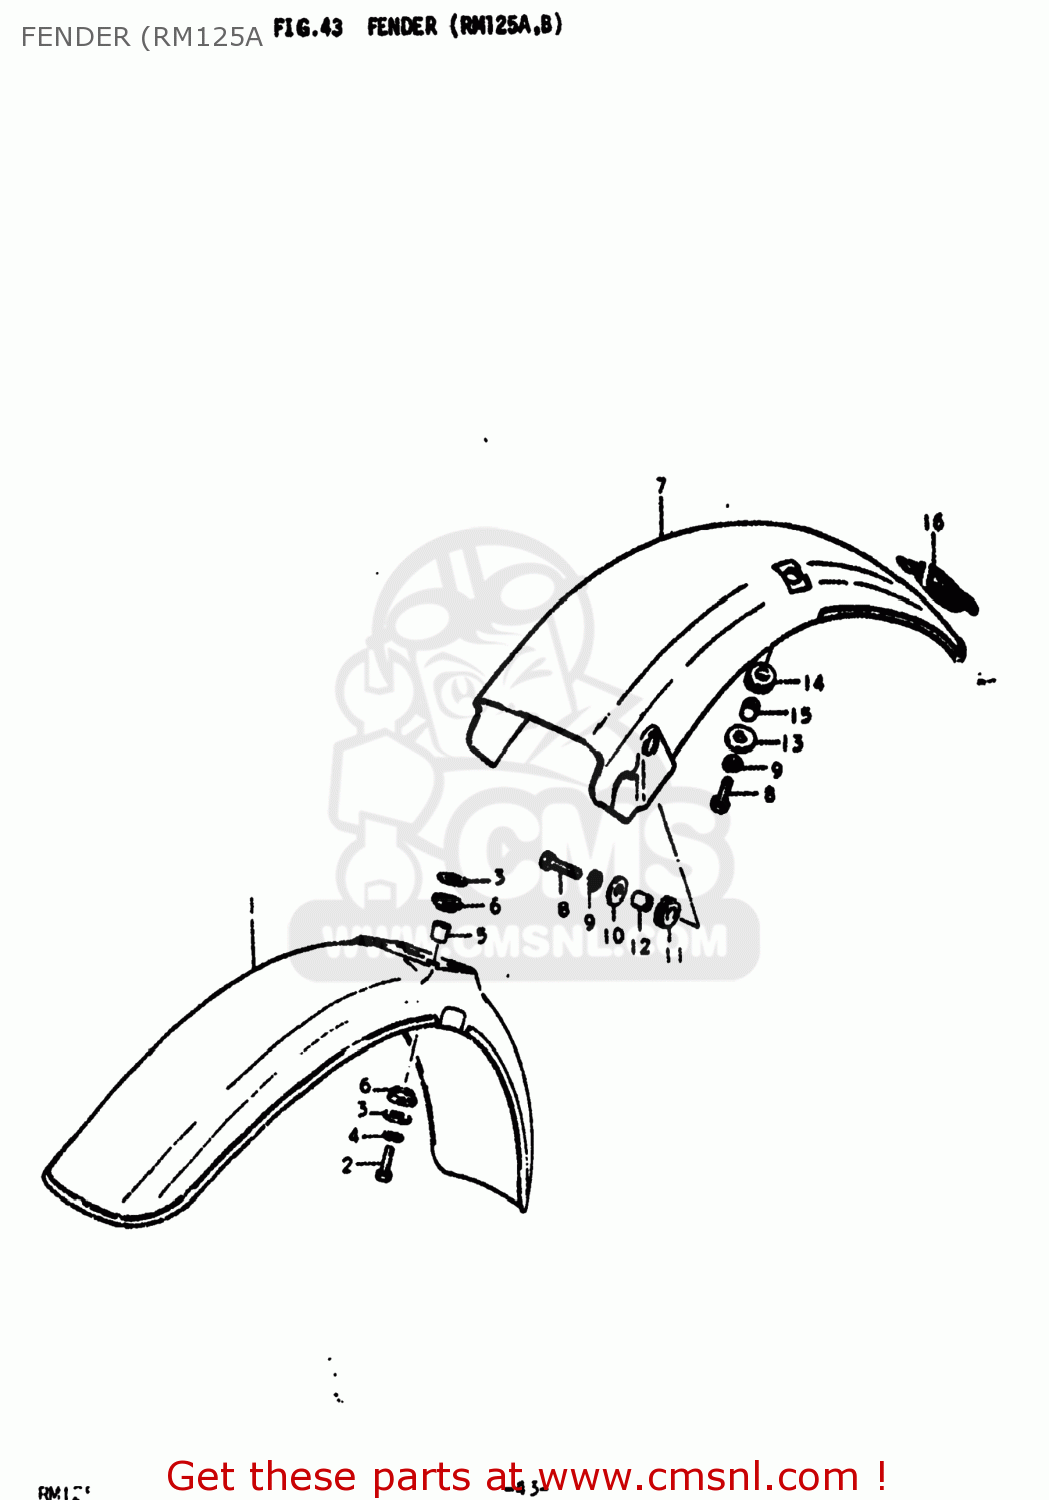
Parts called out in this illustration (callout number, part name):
1	FENDER,FRONT
2	BOLT
3	WASHER (6.5X20X1.2)
4	LOCK WASHER
5	SPACER (6.8X10X10)
6	CUSHION
7	FENDER,REAR
8	BOLT
9	LOCK WASHER
10	WASHER (6.5X20X1.2)
11	CUSHION
12	SPACER(6.1X9X7.5)
13	WASHER (6.5X24X1.6)
14	CUSHION
15	SPACER
